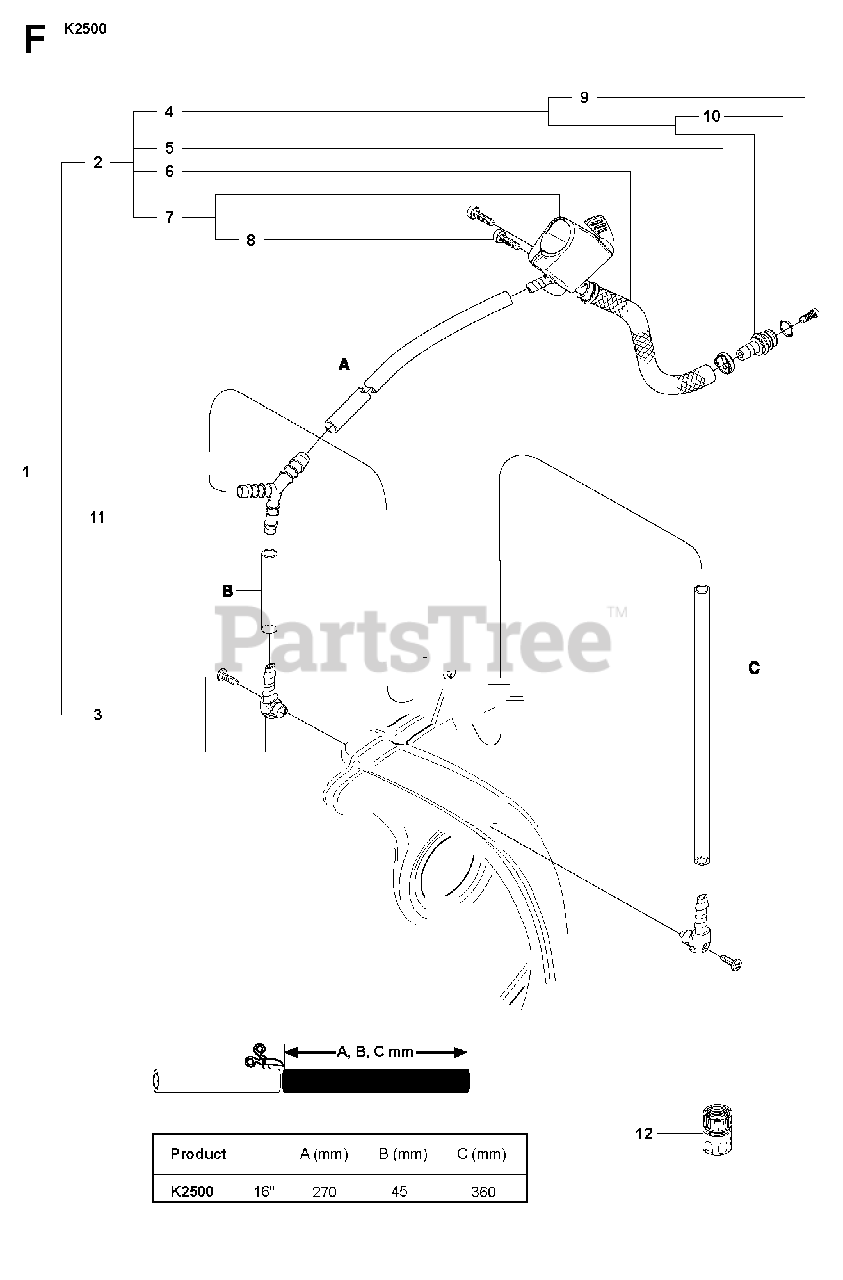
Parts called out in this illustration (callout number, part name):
1	HOSE KITIncl. 2, 3, 11
2	HOSE ASSYIncl. 4, 5, 6, 7
4	NIPPLEIncl. 9
5	HOSE CLAMP
6	HOSEL=230mm
7	VALVE ASSYIncl. 8
10	O-RING
12	COUPLER
